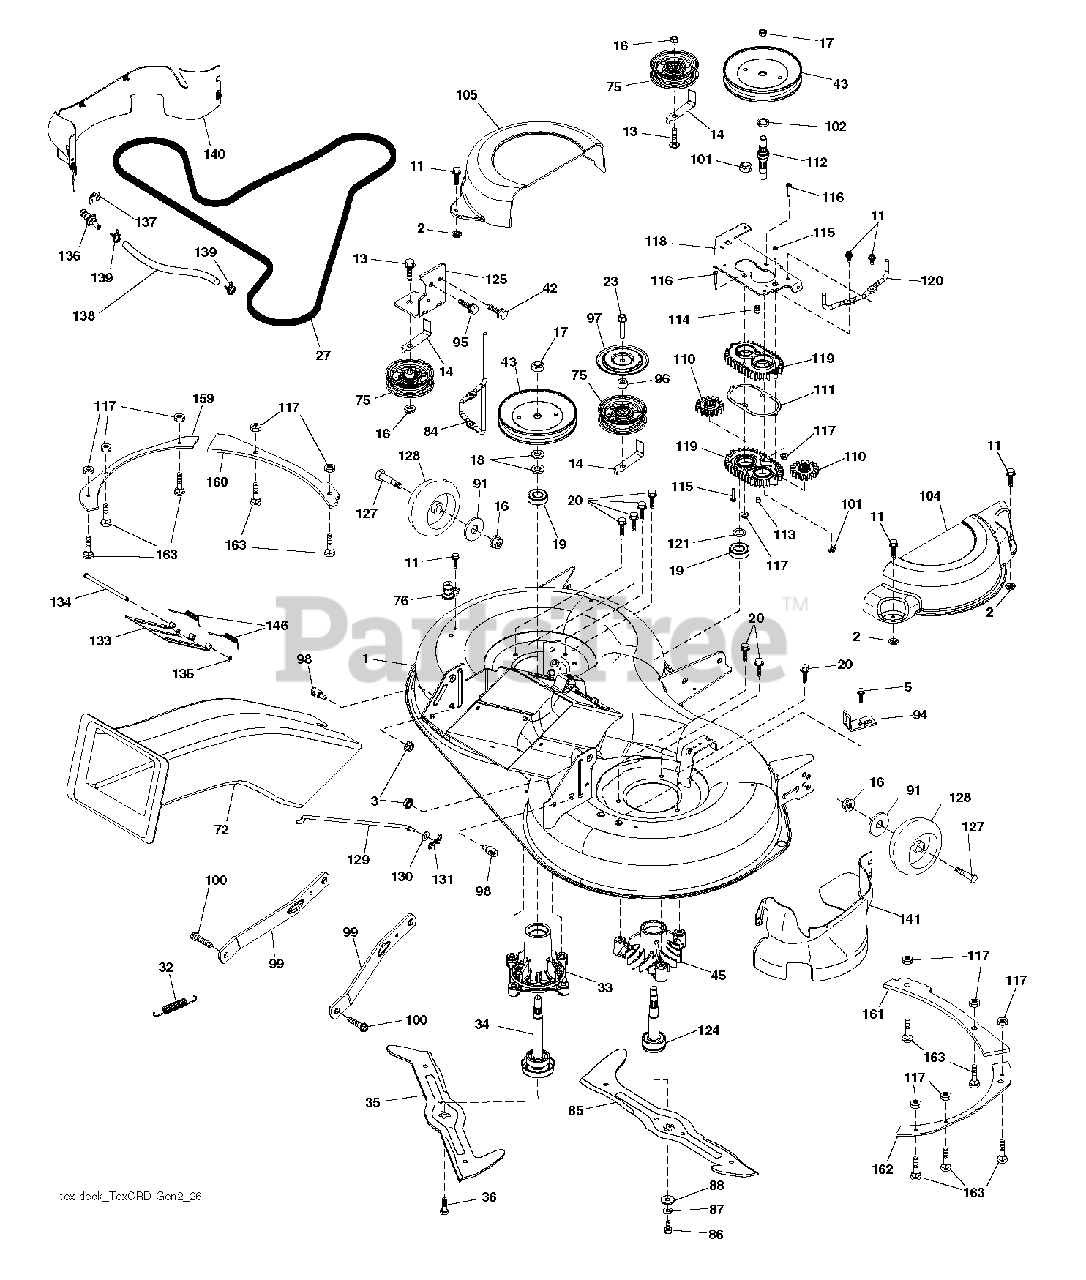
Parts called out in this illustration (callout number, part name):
1	DECK SVC 107HP.EZMUL.498
2	PALNUT 1/4
3	NUT LOCK HEX FLANGE 5/16-18
5	BOLT.5/16HEX.WHS.HD
11	SCREW.1/4-20X5/8
13	BOLT.3/8-16X1.50
14	KEEPER, BELT IDLER
16	NUT LOCK FLG 3/8-16 UNC
17	NUT.FLANGE.LOCK.TOP
18	WASHER.SPACER.MANDREL
20	SCREW, WASHER HEAD
23	SCREW LT
27	BELT BELT. ELECTRIC MOWER DRIV
32	SPRING 107CM & 97CM ELECTRIC D
33	HOUSING.MANDREL.REV.TALL.N/GRS
34	SHAFT ASM.REV.TALL.N/GREASEBL
35	BLADE.107.LH.SINGLE.NON.QD
36	BOLT.WASHER.ASM.7/16-2
42	SCREW
43	PULLEY PULLEY MANDREL 5.438 PD
45	RP HOUSING.MANDREL.REV.REVS.
72	CHUTE.107/97.TEX.GEN2.TRIMMED
75	FLAT IDLER PULLEY
76	1/2" BARB.DECK.WASHOUT.PORT
84	KEEPER KEEPER. LH MANDREL BELT
85	BLADE.107.RH.SINGLE.NON.QD
86	BOLT.3/8-24X1.25GR8. LHTHRD
87	LOCKWASHER
88	WASHER.BLADE
91	WASHER
94	BRKT.CLUTCH.CABLE
95	SCREW, 3/8-16X3/4
96	SPACER
97	PROTECTOR
98	STUD.FASTNER.W/ANTI-ROTATE
99	ARM.SUSPENSION.MOWER.R
100	BOLT.SHOULDER
101	NUT.CROWNLOCK.9/16 -18.UNC
102	SPACER BEARING
104	COVER.MANDREL.107.RH.GEN.2
105	COVER.MANDREL.107.LH.GEN.2
110	GEAR GEAR OUTPUT
111	GASKET GASKET GEARCASE
112	SHAFT SHAFT. CRD GEARCASE ADAP
113	PLUG PLUG OIL
114	VALVE VALVE RELIEF
115	SCREW
116	BOLT.CARIGE.SS.1/4-20X1.75GR5
117	NUT T
118	ARM ARM. CLUTCHING 107 TEX CRD
119	GEARCASE GEARCASE SUBASM
120	KEEPER KEEPER. RH MANDREL BELT
121	WASHER WASHER
124	SUB.ASM.REVERSE.THREAD.REV
125	BRACKET
127	BOLT.SHOULDER.3/8-16X3-5/8.
128	WHEEL. GUAGE RALLY
129	ROD ROD. SWAY CRD GEN II
130	WASHER
131	PIN.COTTER.5/16.BOW TI
133	COVER DOOR.107 CM CRD EZ MULCH
134	PIN PIN.HINGE
135	E-RING.5/16"
136	PLUG WASHOUT PORT HOOKUP
138	107.WASHOUT.PORT.HOSE (2 2)
139	HOSE.3/8.CLAMP (2 2)
140	GUARD FRENCH 107 TEX ASSEMBLY
141	GUARD SUBASM. 107 TEX GEN 2 RH
146	SPRING SPRING: EZ MULCH DOOR
163	BOLT
